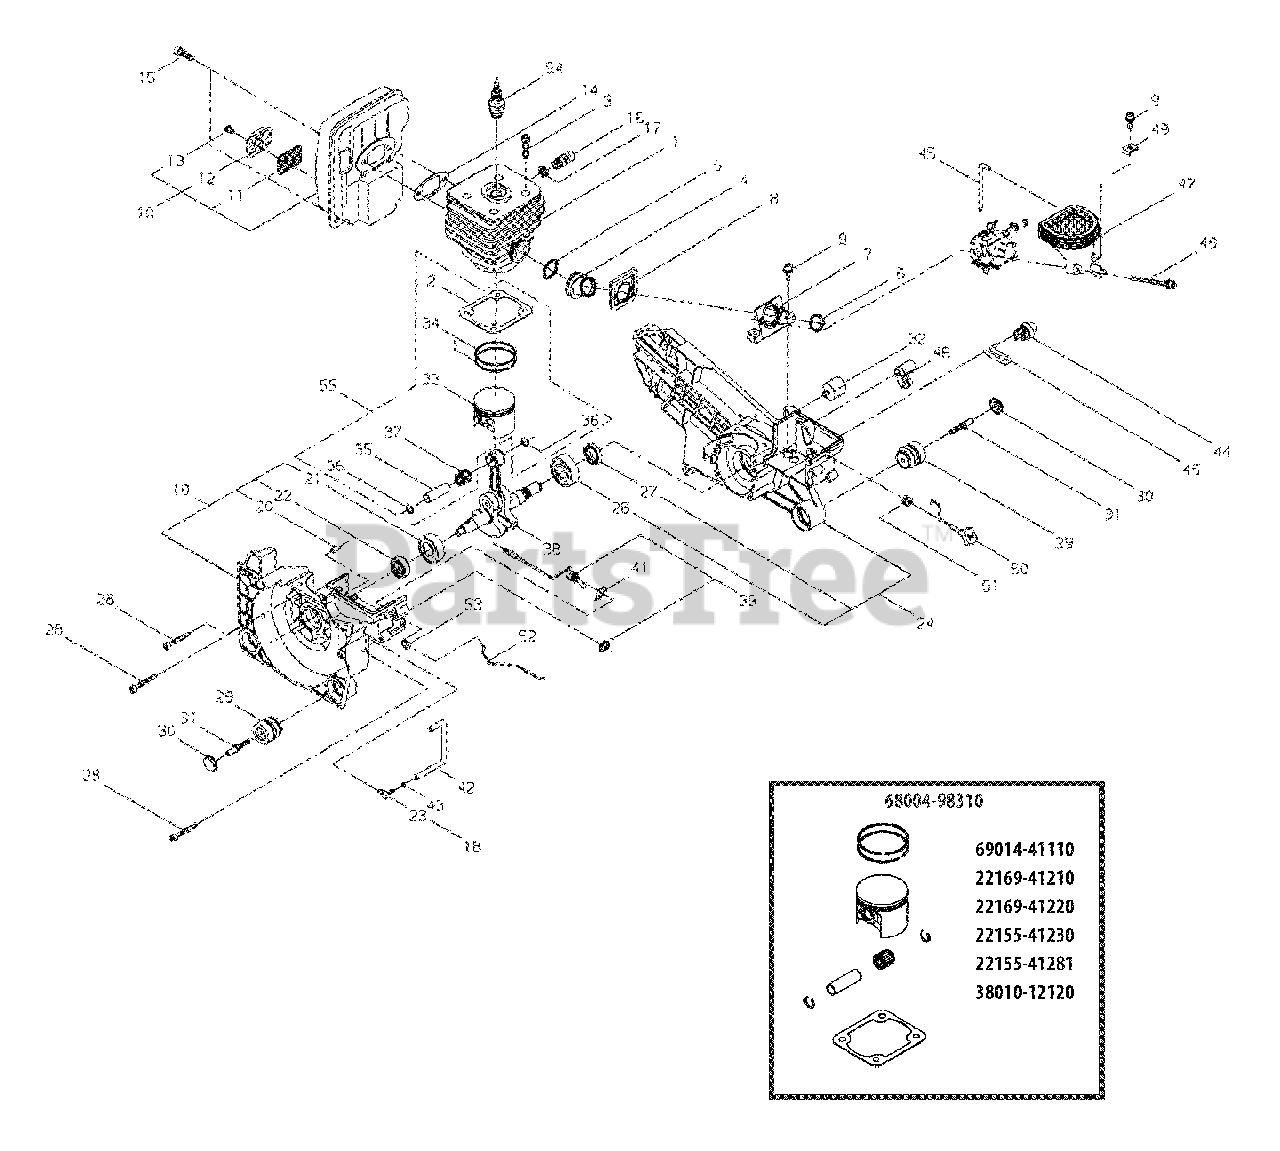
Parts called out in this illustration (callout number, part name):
1	CYLINDER
2	GASKET
3	BOLT
4	BOOT
5	SPRING
6	SLEEVE
8	SEAL
9	SCREW - 5X14
10	MUFFLER ASSY
11	SCREEN, SPARK ARRESTOR
12	TAIL PLATE
13	SCREW - 5X8
14	GASKET
15	SCREW - 6X20
16	VALVE, DECOMPRESSION
17	GASKET
18	CRANKCASE ASSY - LEFT
20	PIN - LOCATING
21	BEARING, BALL - 6202
22	SEAL, OIL
23	CONNECTOR, PIPE
24	CRANKCASE ASSY - RIGHT
26	BEARING, BALL - 6203C3
27	SEAL, OIL
28	BOLT - 5X35
29	CUSHION
30	PLUG
31	BOLT
32	CUSHION
33	PISTON
34	RING, PISTON
35	PIN, PISTON
36	RING, RETAINING
37	BEARING, NEEDLE
38	CRANKSHAFT ASSY
39	SWITCH ASSY
41	SWITCH PLATE
42	PIPE - IMPULSE
43	CLIP
44	BULB, PURGE
45	TUBE
46	GROMMET, CABURETOR
47	ELBOW
50	ROD, CHOKE
51	GROMMET
52	ROD, THROTTLE
53	GROMMET
54	SPARK PLUG -- CJ-6Y
68004-98310	PISTON ASSY
